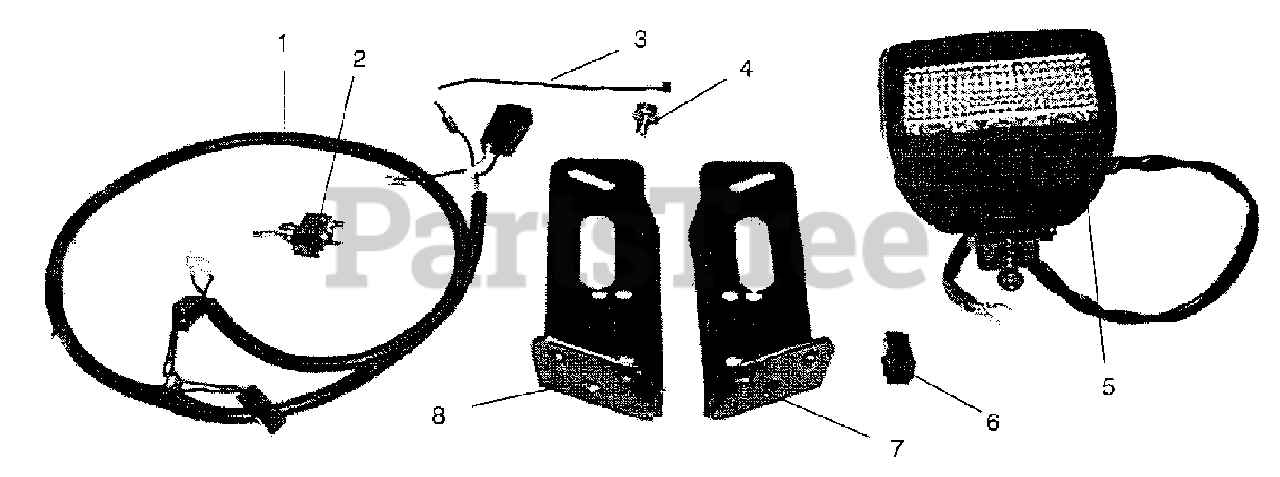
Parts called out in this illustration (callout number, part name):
1	Headlight Harness
2	Headlight Switch
3	Cable Tie
4	3/8" x 1/2" Tapping Screw
5	Headlight
7	Right Hand Light Mount Bracket
8	Left Hand Light Mount Bracket
